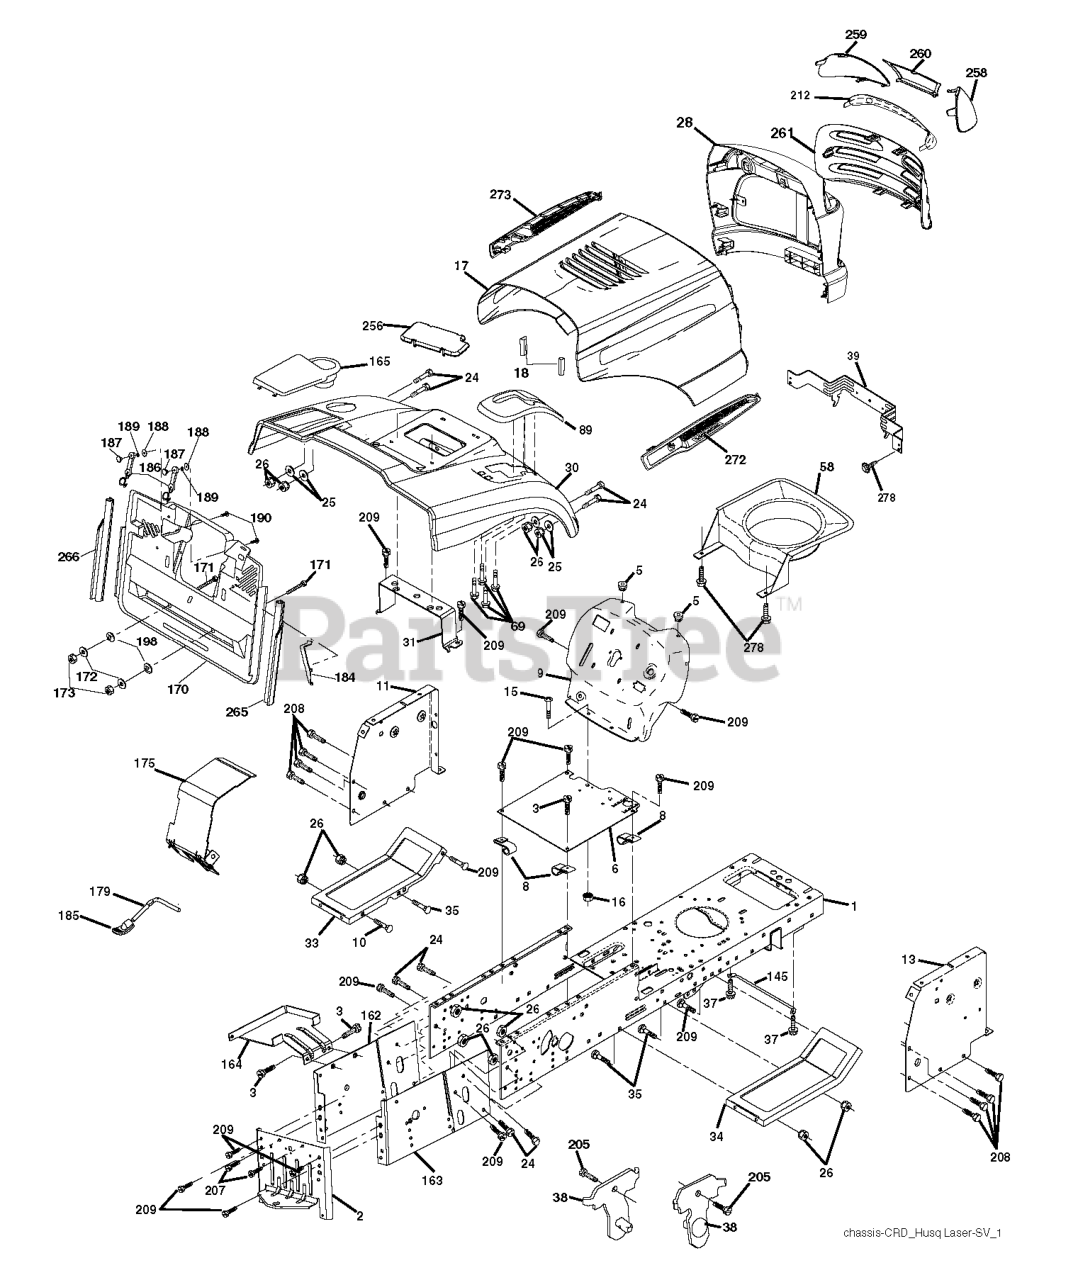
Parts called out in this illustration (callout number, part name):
2	DRAWBAR
3	SCREW 3/8-16X3/4
5	BUMPER.RUBBER.HOOD
6	PLATE
8	CLIP,INSULATOR
9	DASH.SLK.LT.PL.CC.NA.NHM.CE
10	BOLT D
11	PANEL.DASH.LH.LTX
13	PANEL ASM, DASH RH
15	Screw, Machine, Truss Head 5/16-18 UNC x 3/4
16	NUT
17	VENT.HOOD.LASER.III
18	BUMPER.HOOD.LARGE.1.75"
25	WASHER
26	NUT
30	CONSOLE.CRD.AUTO.GRY
31	BRACKET SUPPORT FENDER
33	FOOTREST.PNT.LH.BLACK
34	FOOTREST, RH
37	Screw 5/16-18 x 1/2 Hex, Self Tapping 5/16-18 x 1/2
38	BRACKET ASM PIVOT MOWER REAR
39	BRACKET PIVOT
69	SCREW.HI-LO.CONSOLE
89	CONSOLE.CRD.6SP.BLACK
145	ROD.PIVOT.HOOD
162	BRACKET
163	BRACKET EXTEN CHASSIS RH CRD
165	COVER.BATTERY.CRD.BLACK
172	WASHER
175	DOOR TRAP
179	ROD PIVOT FBI
184	BRACKET.ACTUATOR.BAGGER.SRD
186	LATCH ASSY
187	WELDNUT
189	LOCKWASHER #10
190	SCREW
207	SCREW, 5/16-18 X 1/2
208	SCREW 3/8-16X1/2
209	SCREW, 3/8-16X3/4
212	INSERT.LENS.REFLECTIVE
256	COVER FENDER CRD
258	LENS LH
259	LENS LH
260	COVER.LENS.HUSQ.LASER
265	SEALING
266	SEALING
272	VENT.HOOD.LASER.
273	VENT.HOOD.LASER.
278	SCREW.#10 X 0.750.BOS
